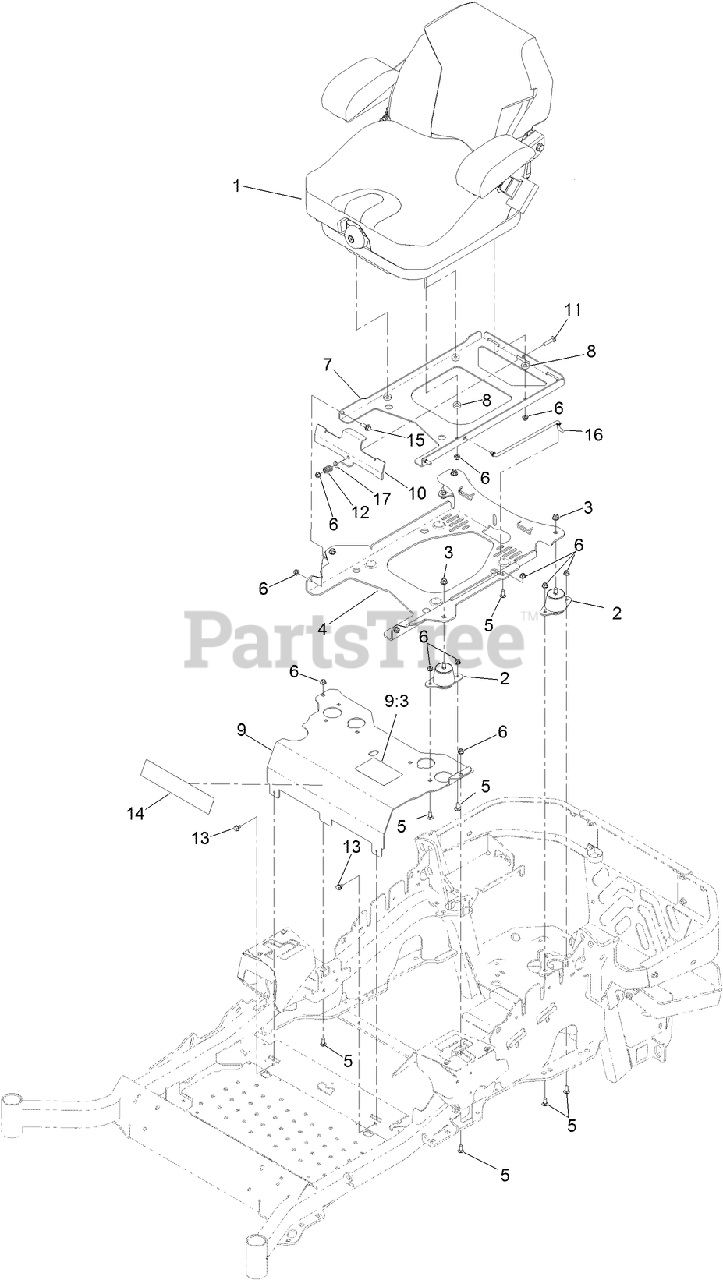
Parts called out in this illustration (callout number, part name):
2	ISOLATOR-SEAT
3	NUT-HF, NI
4	PLATE-TILT, SEAT SUPPORT
5	SCREW-CARR
6	NUT-HF, NI
7	PLATE-FRAME, SEAT
9	SEAT MOUNT ASM
9:3	DECAL-SERVICE AID
10	PLATE-LATCH, SEAT
11	BOLT-CARR
12	SPRING-COMPRESSION
13	SCREW
14	DECAL
15	SCREW-SHOULDER
16	ROD-PROP
17	WASHER-PLAIN
